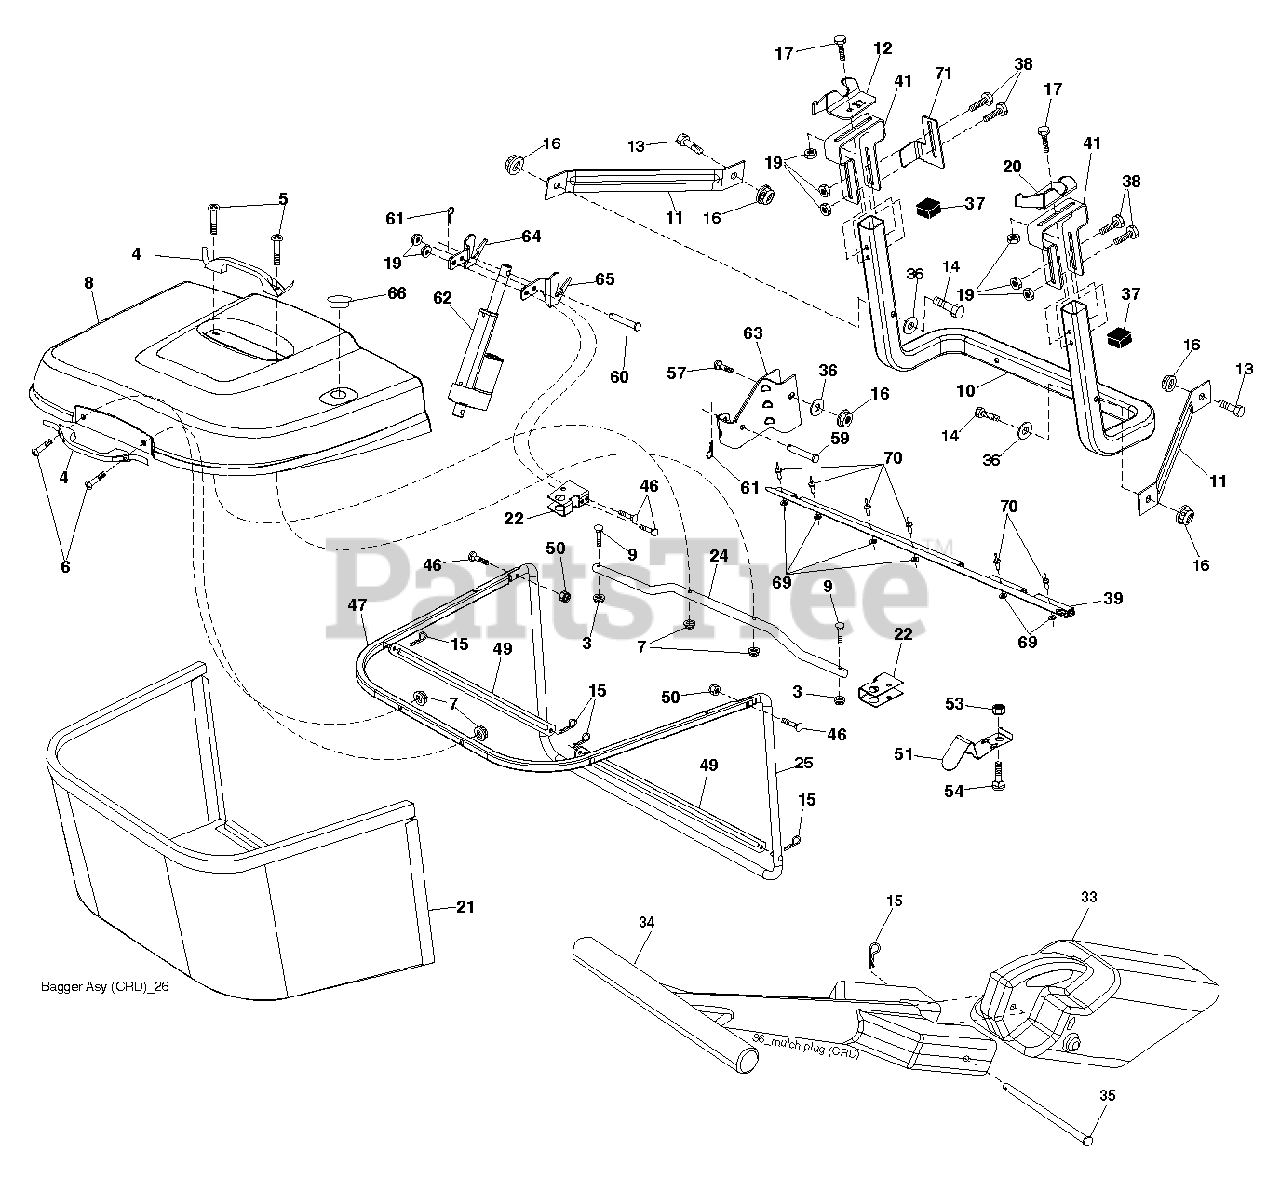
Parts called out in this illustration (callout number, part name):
3	NUT T
5	SCREW.PAN.HEAD
11	BRACKET
14	BOLT-HEX EAK
15	RETAINER-SPRNG RB
16	NUT LOCK FLG 3/8-16 UNC
17	BOLT
19	NUT LOCK HEX FLANGE 5/16-18
20	BRKT.PIVOT.RH.CRD
21	BAGGER.ASM.CRD.2007
22	BRACKET.BAGGER.SD.
24	TUBE
33	MULCHING.PLUG.1078.CRD.NON-TEX
35	PIN
38	BOLT.5/16-18X2.5
39	SEAL.BAGGER.CRD
41	BRACKET.BAGGER.SD.
46	BOLT.CARRIAGE.5/16-18
50	NUT.71038.31-18.HEX.NYLOCK
53	NUT
54	BOLT
61	RETAINER M
